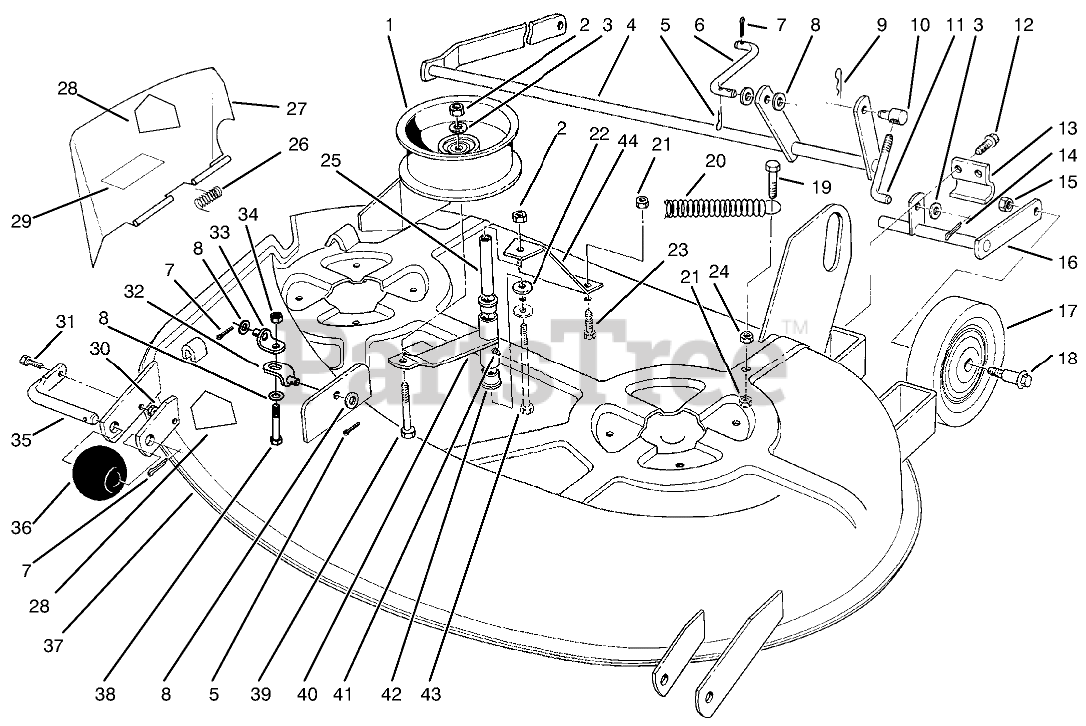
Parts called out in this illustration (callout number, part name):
1	Pulley-Idler
2	NUT-LOCK, NI
3	WASHER-FLAT
4	Shaft-R.H.
5	PIN-COTTER
6	LINK-REAR
7	Hairpin
8	WASHER-FLAT
9	Hairpin
10	TRUNNION
11	ROD-LIFT
12	Bolt
13	Camp
14	PIN-COTTER
15	Nut-Hex
16	Shaft-L.H.
17	WHEEL
18	BOLT-SHOULDER
19	SCREW-HH
20	SPRING-EXTENSION
21	NUT-LOCK, NI
22	WASHER
23	SCREW-HH
24	NUT-HEX
25	SPACER
26	SPRING
27	DISCHARGE CHUTE/DECAL
28	DECAL-DANGER
29	DECAL-DANGER
30	NUT-LOCK, NI
31	SCREW-HH
32	BRACKET-LIFT, LOWER
33	BRACKET-LIFT, UPPER
34	NUT-JAM
35	SHAFT-ROLLER
36	ROLLER
37	38 DECK W/DECALS
38	SCREW-HH
39	SCREW-HH
40	Arm-Idler
41	FITTING-GREASE
42	BUSHING
43	SCREW-HH
44	Brace
